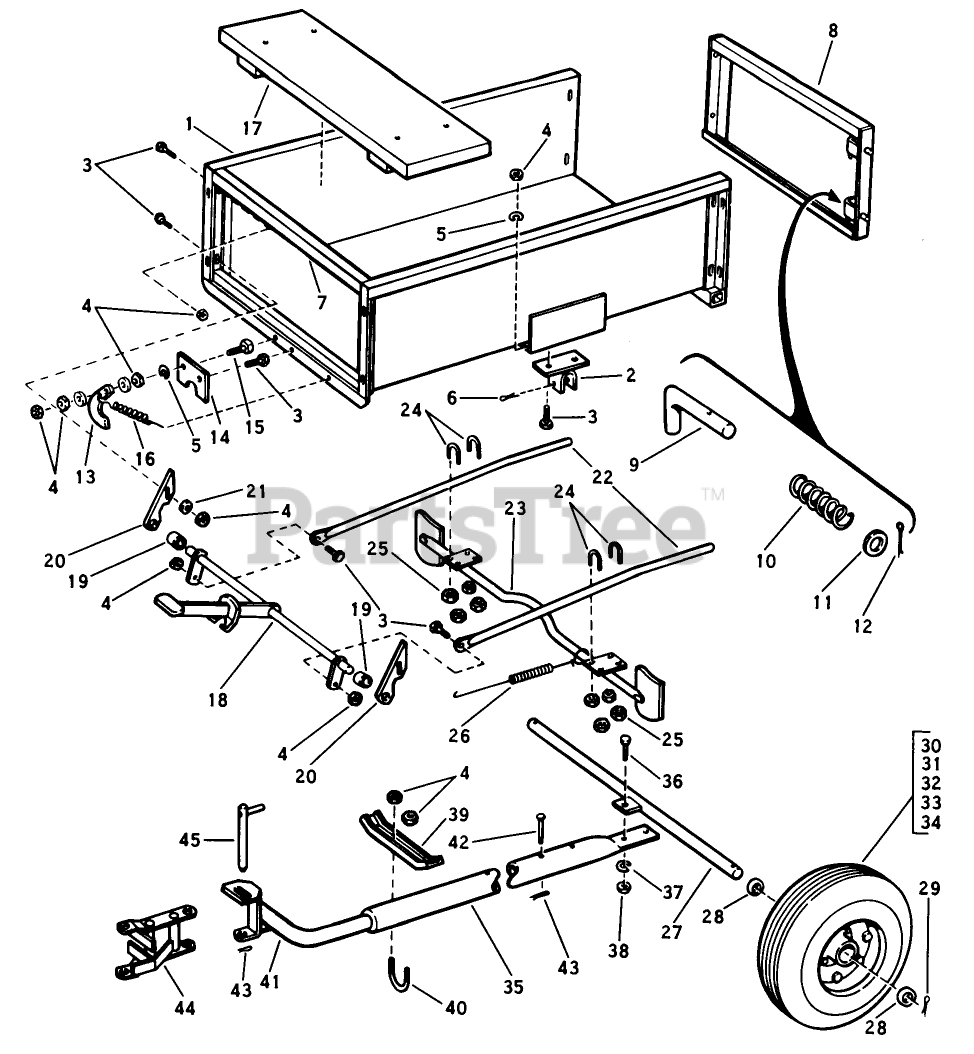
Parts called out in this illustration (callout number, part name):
1	Body Assembly
2	Saddle Assembly
6	Cotter Pin 1/4 x 2 Lg.
7	Front Gate Assembly
8	Rear Gate Assembly
10	Lever-Flex*
12	Plate-Support
13	Tongue Latch Handle
14	Latch Plate
15	Capscrew 3/8-16 x 1 Lg.
18	Torque Rod Assembly
23	Brake Bar Assembly
25	Hex Nut
27	Axle Assembly
29	Cotter Pin 1/4 x 2 Lg.
30	Wheel, Tire and Tube Assy
31	Wheel Assembly
33	Tire 4.00 x 8
34	Tube 5.00 x 8
36	Capscrew 1/2-13 x 1-1/4 Lg.
41	Hitch Assembly
44	Bar Assy
45	Hitch Pin
